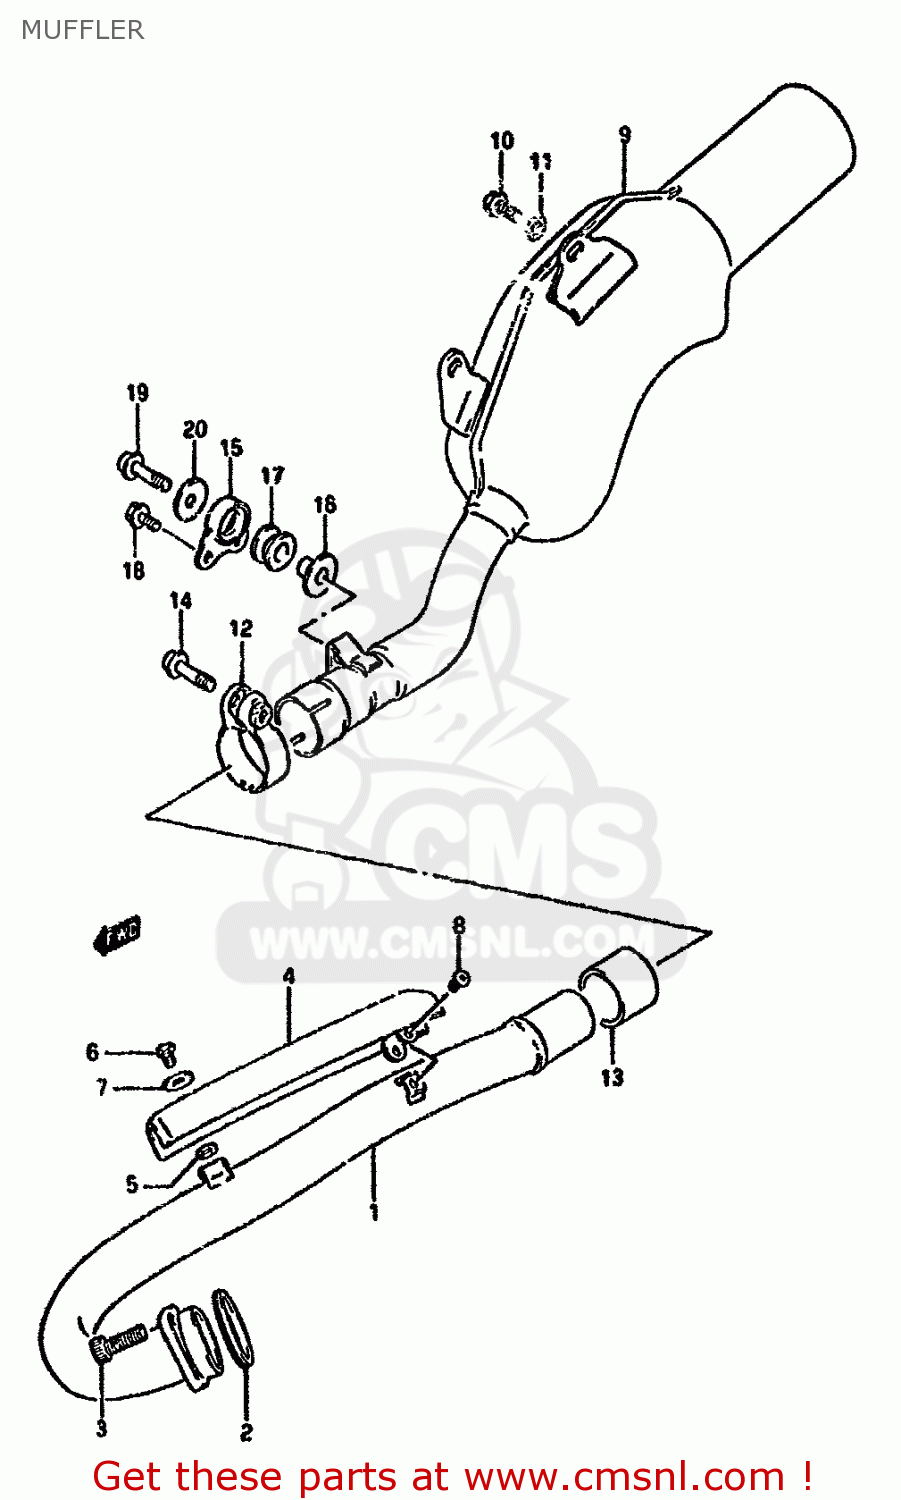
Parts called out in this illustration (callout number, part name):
1	PIPE,EXHAUST
2	GASKET (NAS)
3	BOLT
4	COVER,EXHAUST PIPE
5	GASKET(5.8X13X1.4) (NAS)
6	SCREW(6X10)
7	WASHER(6.5X18X1)
8	SCREW
9	MUFFLER ASSY
10	BOLT(8X20)
11	WASHER (8.5X19X2.3)
12	CLAMP,PREMUFFLER CONNECTOR,L
13	CONNECTOR,MUFFLER JOINT
14	BOLT
15	DAMPER,MUFFLER SUPPORT
16	SPACER(8.6X12X17.5)
17	CUSHION
18	BOLT
19	BOLT 8X35
20	WASHER (8.5X20X1.6)
